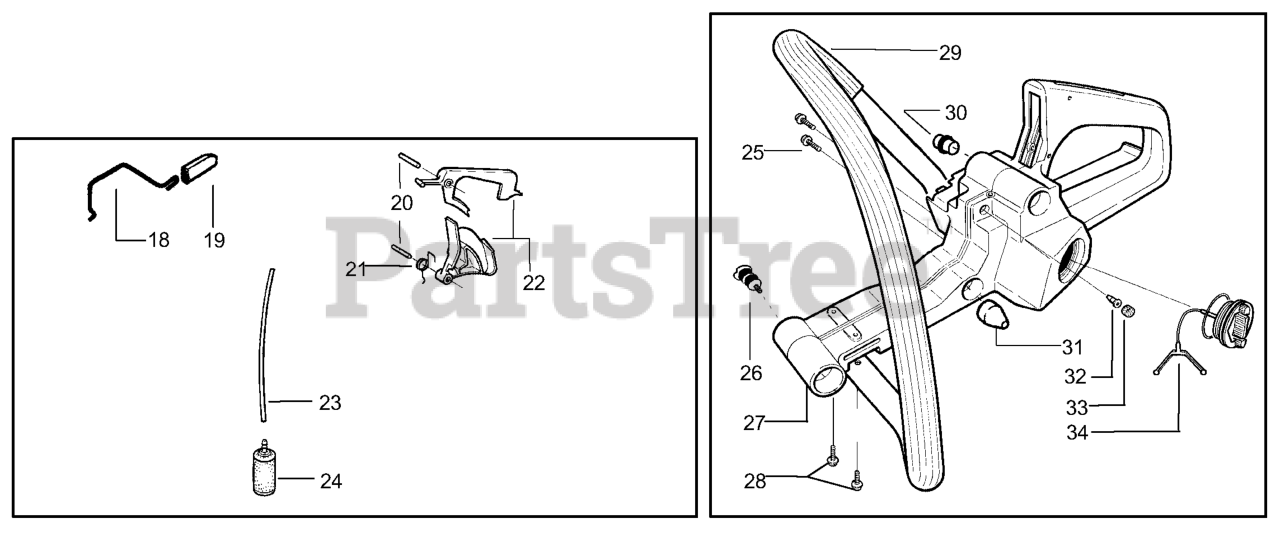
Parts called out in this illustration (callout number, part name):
18	THROTTLE SHAFT 36/41
19	THROTTLE ACTUATOR 36/41
20	PIN,TRIGGER 36/41
21	TRIGGER SPRING 36/41
22	THROTTLE TRIGGER-KIT
23	HOSE. FUEL
24	FUEL PICK-UP
27	TANK HANDLE ASSY
28	SCREW,FRONT HBAR 36/41
29	FRONT HANDLE
30	FRONT HANDLE ISOLATOR
31	SHOCK MOUNT(X2) 36/41
32	VALVE-CHECK (DUCKBILL)
33	BRONZE PLUG
34	FUEL CAP/GREEN
